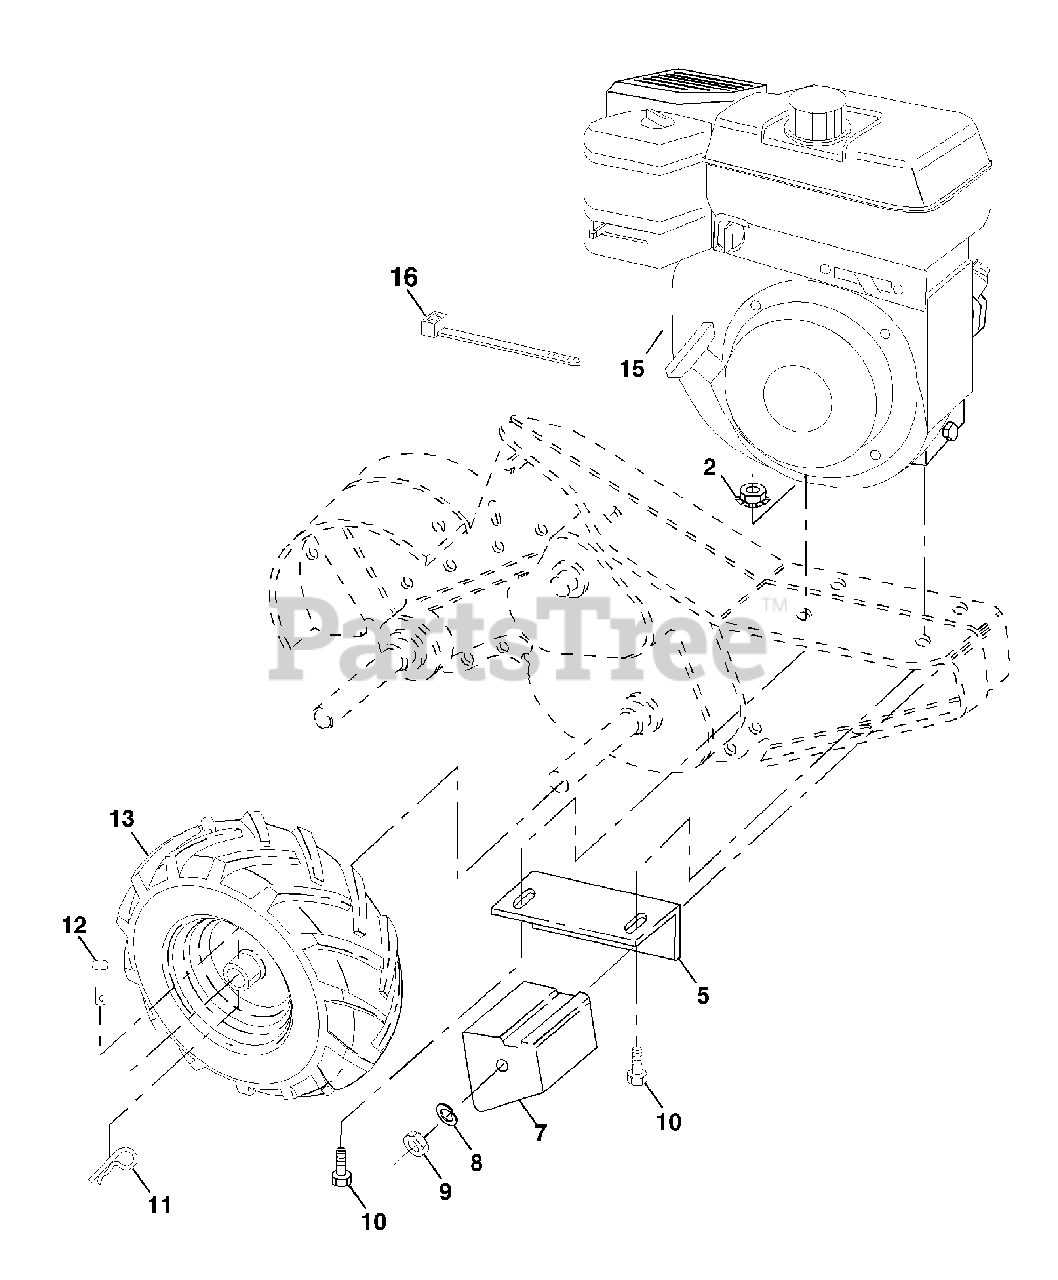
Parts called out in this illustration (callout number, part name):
2	Nut, Lock Hex Flange
5	Bracket, Reinforcement
7	Counter Weight, R.H.
8	Washer, Lock 3/8
9	Nut, Hex 3/8-16
10	Bolt, Hex 5/16-18 x 1-1/2
11	Clip, Hairpin
12	Rivet, Drilled
13	Tire
13	Rim
13	Tire Valve
16	Tie Cable
